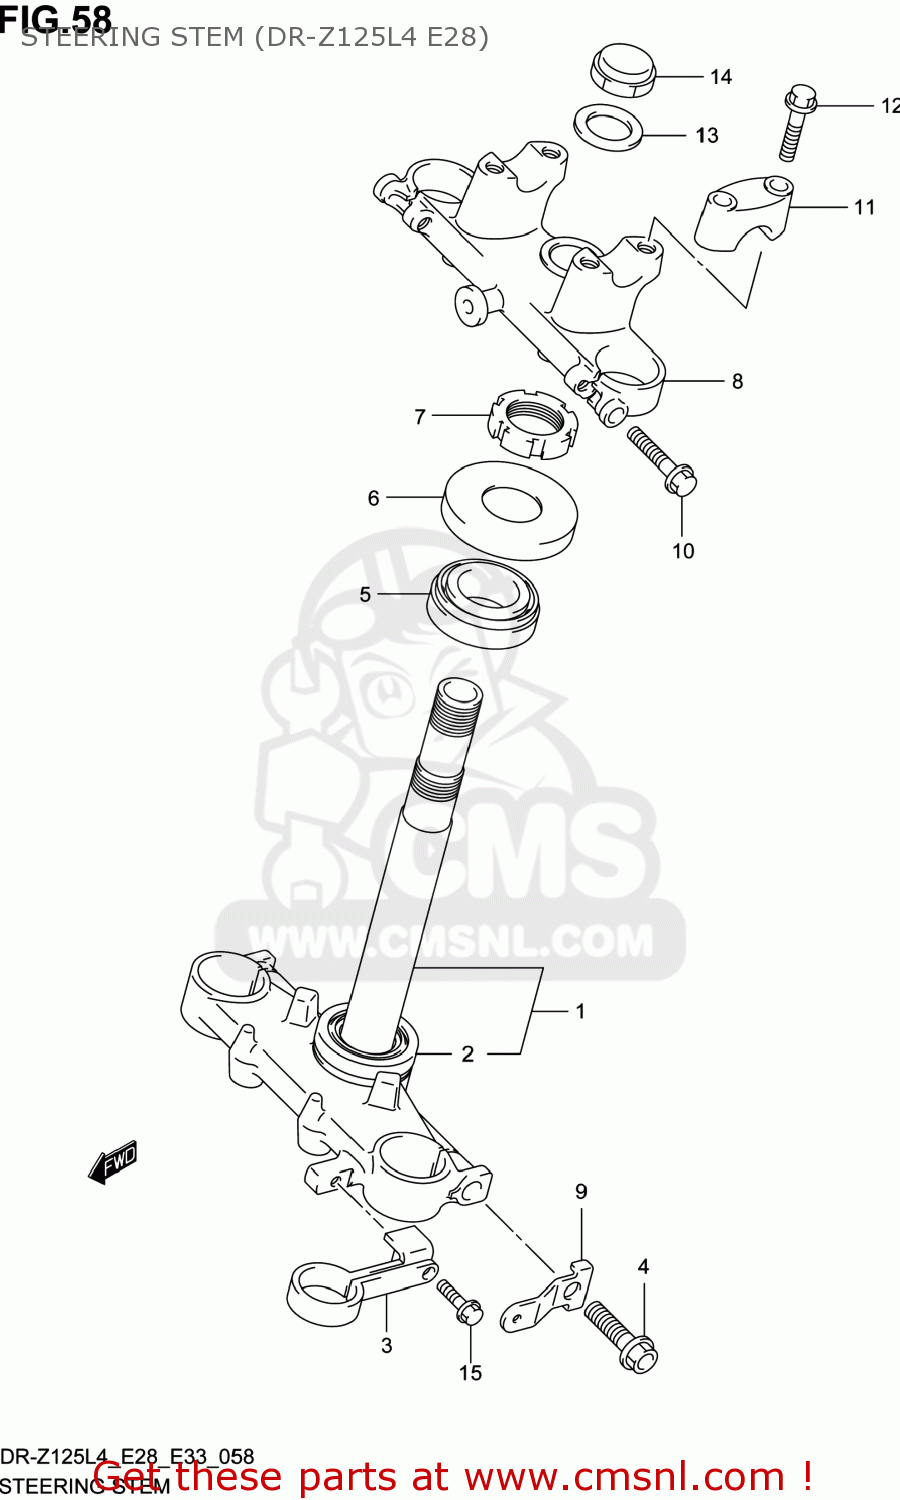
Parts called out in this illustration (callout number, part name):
1	STEM,STEERING
2	BEARING(26X47X15)
3	GUIDE,FR BRAKE HOSE
4	BOLT
5	BEARING(25X47X15)
6	SEAL,STEERING UPR DUST
7	NUT,STEERING
8	BRACKET,UPR
9	BRACKET,FR SIDE RR
10	BOLT
11	HOLDER,HANDLE
12	BOLT
13	WASHER
14	NUT
15	BOLT
